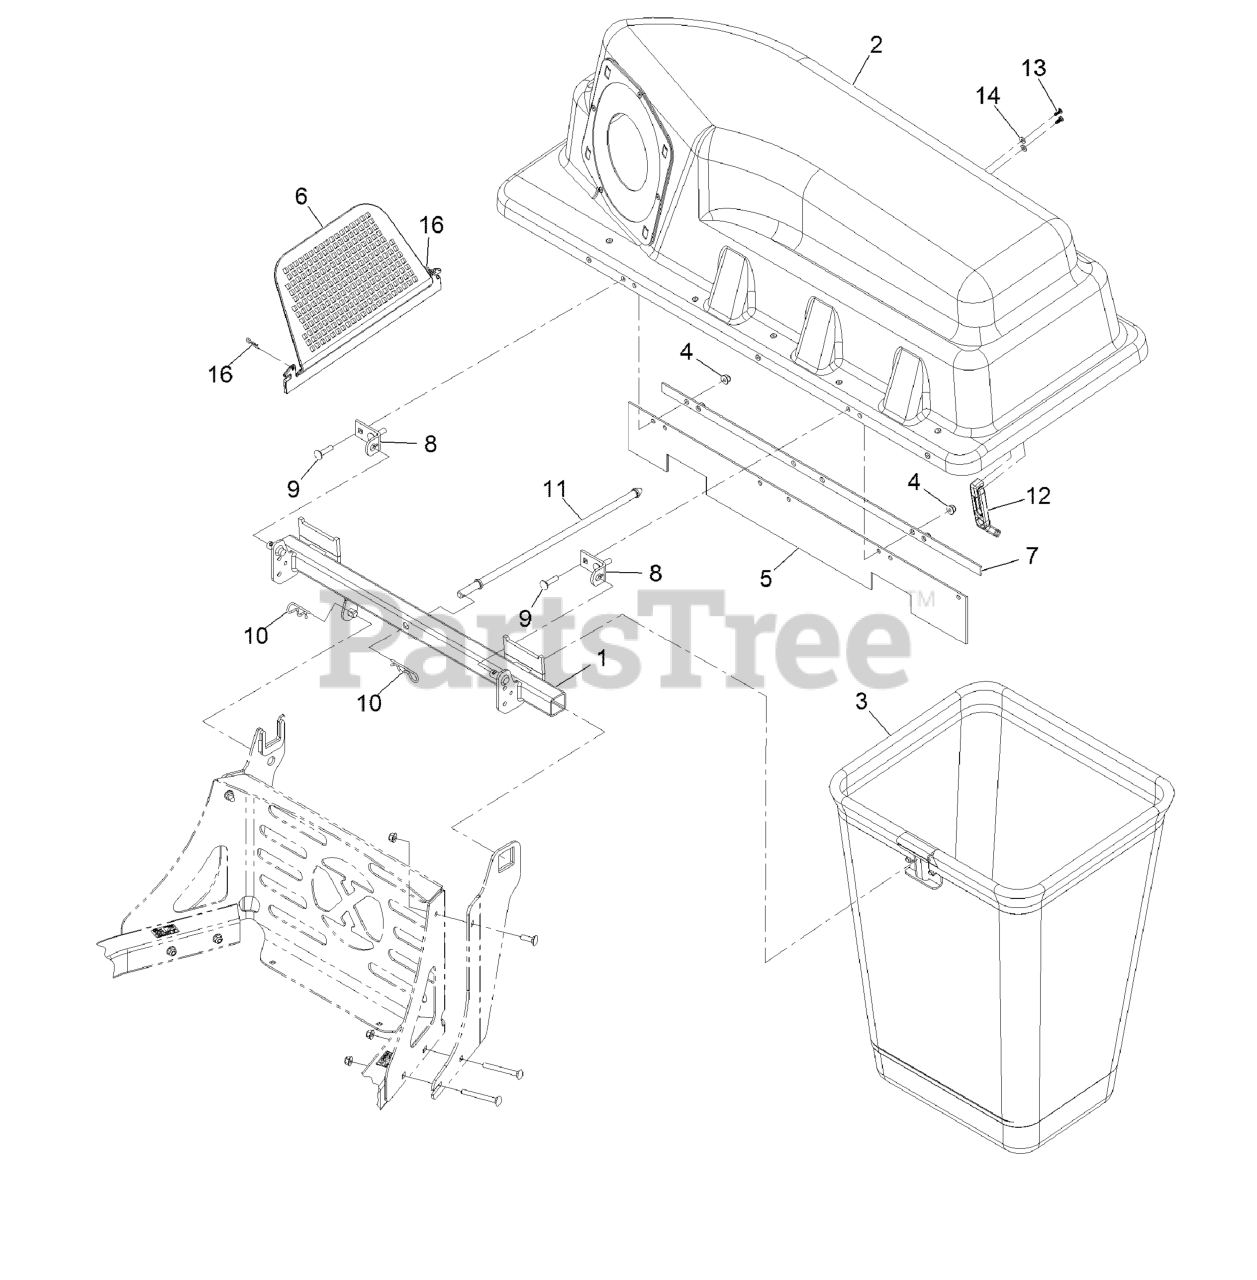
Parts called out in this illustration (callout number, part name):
1	FRAME PIVOT ASM
2	BAGGER HOOD ASM
3	BAG AND FRAME ASM
4	NUT-HF, NI
6	SCREEN-BAGGER
7	PLATE-BACKING
8	BRACKET-PIVOT, HOPPER
9	Bolt-Carriage 5/16-18 X 1 1/4
10	PIN-HAIR
11	ROD-HOLD DOWN, HOOD
12	LATCH-RUBBER
13	SCREW-PLASTITE
14	WASHER-FLAT
